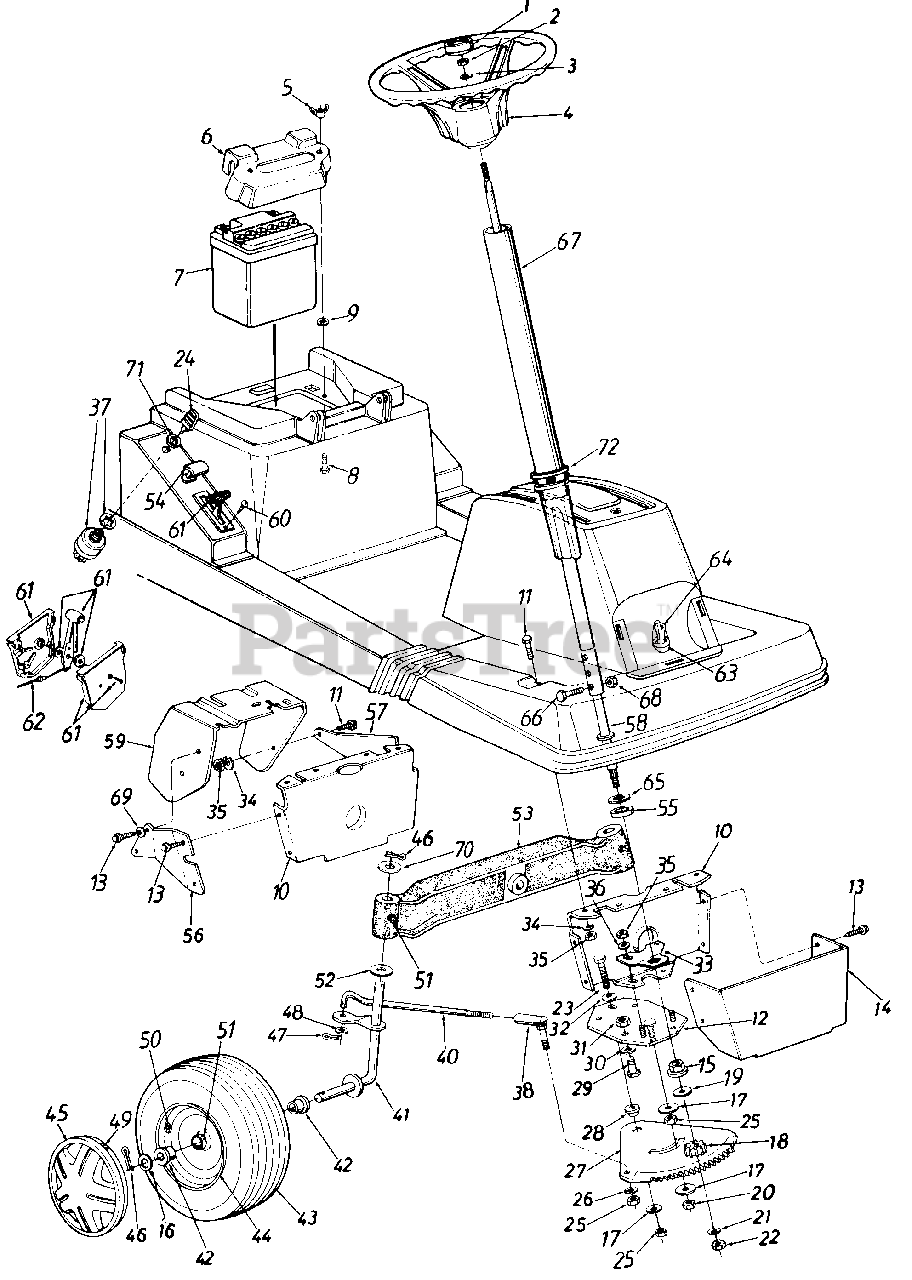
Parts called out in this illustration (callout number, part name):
1	Steering Wheel Cap
2	Hex L-Nut 5/16-24 Thd.
3	Bell-Wash. .345" I.D. x .88" O.D.
4	Steering Wheel Ass'y.
5	Wing Nut 1/4-20 Thd. (Nylon)
6	Battery Hold Down Cover
7	12V Battery
8	Hex Bolt 1/4-20 x 1.75" Lg.
9	Push On Retaining Ring
16	Fl-Wash. .635" I.D. x 1.585"
17	Fl-Wash. .385" x 1.37" O.D.
18	Steering Pinion Gear
19	Fl-Wash. .510" I.D. x 1.0" O.D.
20	Hex L-Nut 3/8-24 Thd.
21	Fl-Wash. .34" I.D. x .68" O.D.
22	Hex Nut 5/16-24 Thd.
23	Hex Bolt 3/8-24 x 1.5" Lg. (Gr. 5)
24	Ignition Key Set
25	Hex Nut 3/8-24 Thd.
26	L-Wash. 3/8" I.D.
27	Steering Gear Segment
28	Shld. Spacer
29	Hex Bolt (Nylon) 1/2-13 x .75" Lg.
30	Fl-Wash. .53" I.D. x .93" O.D.
31	Hex Nut 1/2-13 Thd.
32	Bell-Wash. .385" I.D. x .88"
33	Steering Gear Adjuster
34	L-Wash. 5/16" I.D.
35	Hex Nut 5/16-18 Thd.
36	Spr. Wash. .32" I.D. x .62" O.D.
37	Ignition Switch
38	Ball Joint Ass'y.
40	Steering Tie Rod
41	Front Axle Ass'y.--R.H.
42	Wheel Bearing 12 x 5 Bronze Brg.
42	Wheel Bearing 12 x 5 Ball Brg.
43	Wheel Ass'y. Comp. 12 x 5 Bronze Brg.
43	Wheel Ass'y. Comp. 12 x 5 Ball Brg.
44	Rim Only 12 x 5 Bronze Brg.
46	Cotter Pin 1/8" Dia. x 1.25" Lg.
47	Cotter Pin 1/8" Dia. x 1.0" Lg.
48	Fl-Wash. .385" I.D. x .87" O.D.
49	Spring Clip
50	Air Valve
51	Grease Fitting 12 x 5 Bronze Brg.
52	Fl-Wash. .76" I.D. x 1.49" O.D.
55	Spacer.985" I.D. x 1.25"
59	Clutch Pedal Brkt. Ass'y.
60	Truss Mach. AB-Tap Scr. #10 x .5" Lg.
61	Throttle Control Box Ass'y.
62	Throttle Control Wire 26" Lg.
63	Headlight Socket
64	Lamp
65	Fl-Wash. .64" I.D. x 1.24"
66	Hex Bolt 1/4-20 x 1.25" Lg.
67	Steering Shaft Ass'y.
68	Hex L-Nut 1/4-20 Thd.
69	Bell-Wash. .345" I.D. x .88" O.D.
70	Fl-Wash. .75" I.D. x 1.5" O.D.
71	Ignition Switch Nut
72	Steering Cover Brg.
